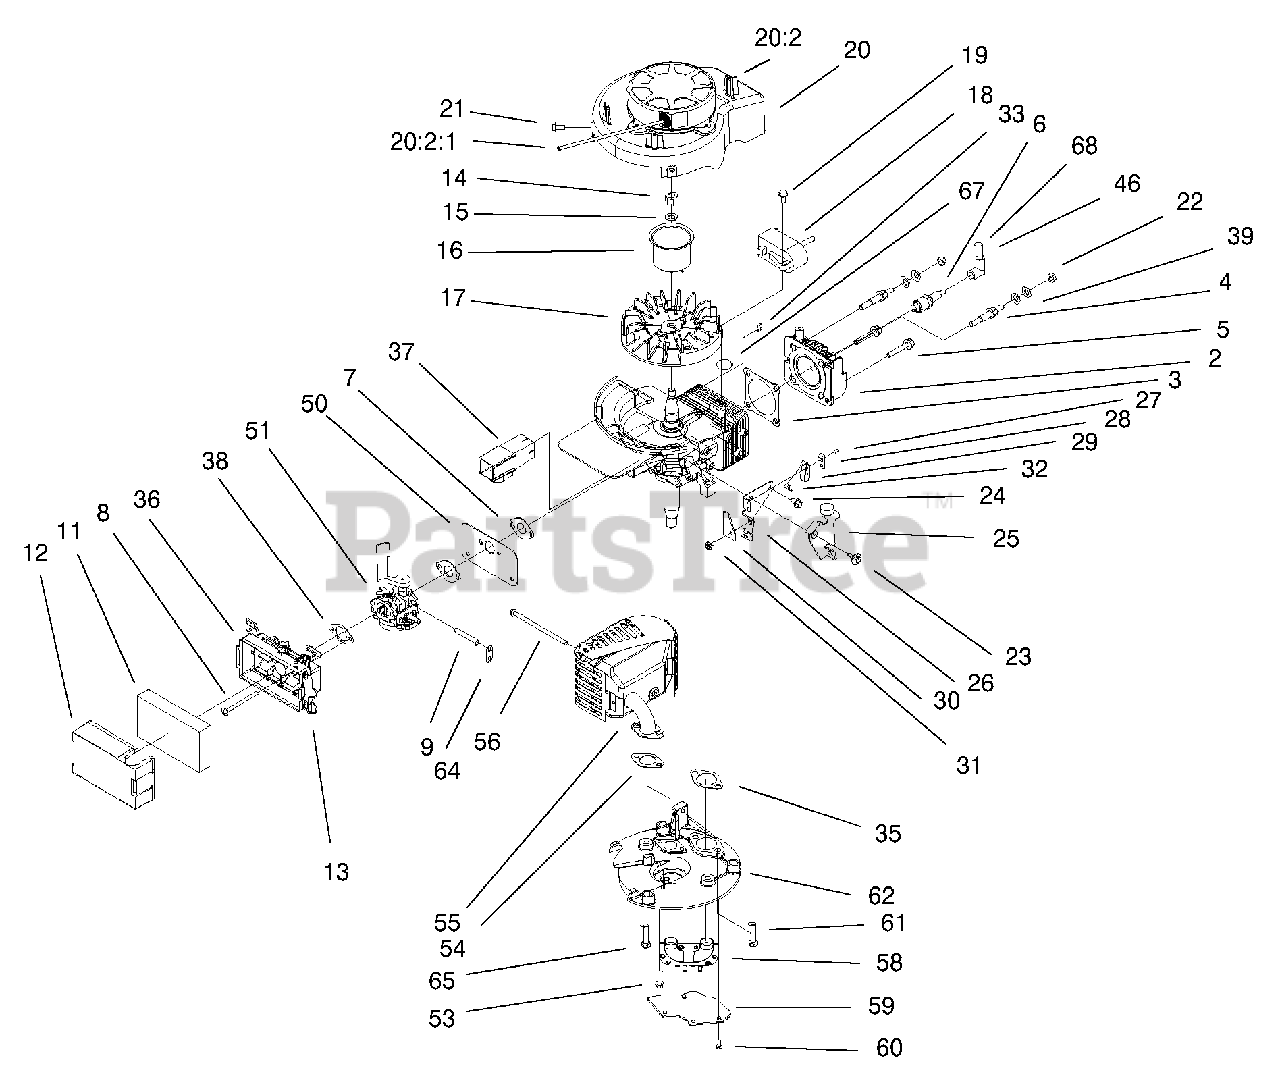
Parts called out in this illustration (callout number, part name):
1	SHORT BLOCK ASM
2	HEAD-CYLINDER
3	GASKET-HEAD
5	BOLT-HEAD
6	SPARK PLUG
7	GASKET-INTAKE
9	HOSE-PRIMER
11	FILTER-AIR
12	COVER-FILTER, AIR
13	RETAINER-COVER, FILTER
15	WASHER-LOCK
16	CUP-STARTER
17	FLYWHEEL
18	Cd Ign
20	SHROUD-RECOIL
20:2	RECOIL ASM
20:2:1	ROPE-RECOIL
21	SCREW-HH
23	SCREW-SHOULDER
24	SCREW-HWH
25	BRAKE PLATE AY EV
26	PLATE-BRAKE
27	RIVET-PLASTIC
28	STRAP-INSULATION
29	STRAP-GROUND
30	STOP-STRAP, GROUND
32	LEAD WIRE-SWITCH, BRAKE
35	GASKET-EXHAUST
36	AIR BASE ASM
37	TUNNEL-INLET
38	GASKET-FILTER
39	WASHER-BELLEVILLE
46	COVER & TERM. AY S
50	SHIELD-CARB E
51	CARBURETOR ASM
55	MUFFLER & GUARD AY E
56	BOLT-CONSOLE
58	PIPE-TRANSFER
59	COVER-MUFFLER E
60	SCREW-HH
61	SCREW-HH
62	PLATE-MUFFLER E MACH
64	HOSE-RETAINER
65	SCREW-HH
67	STRAP-TIE
68	HT LEAD&COVER XEV
